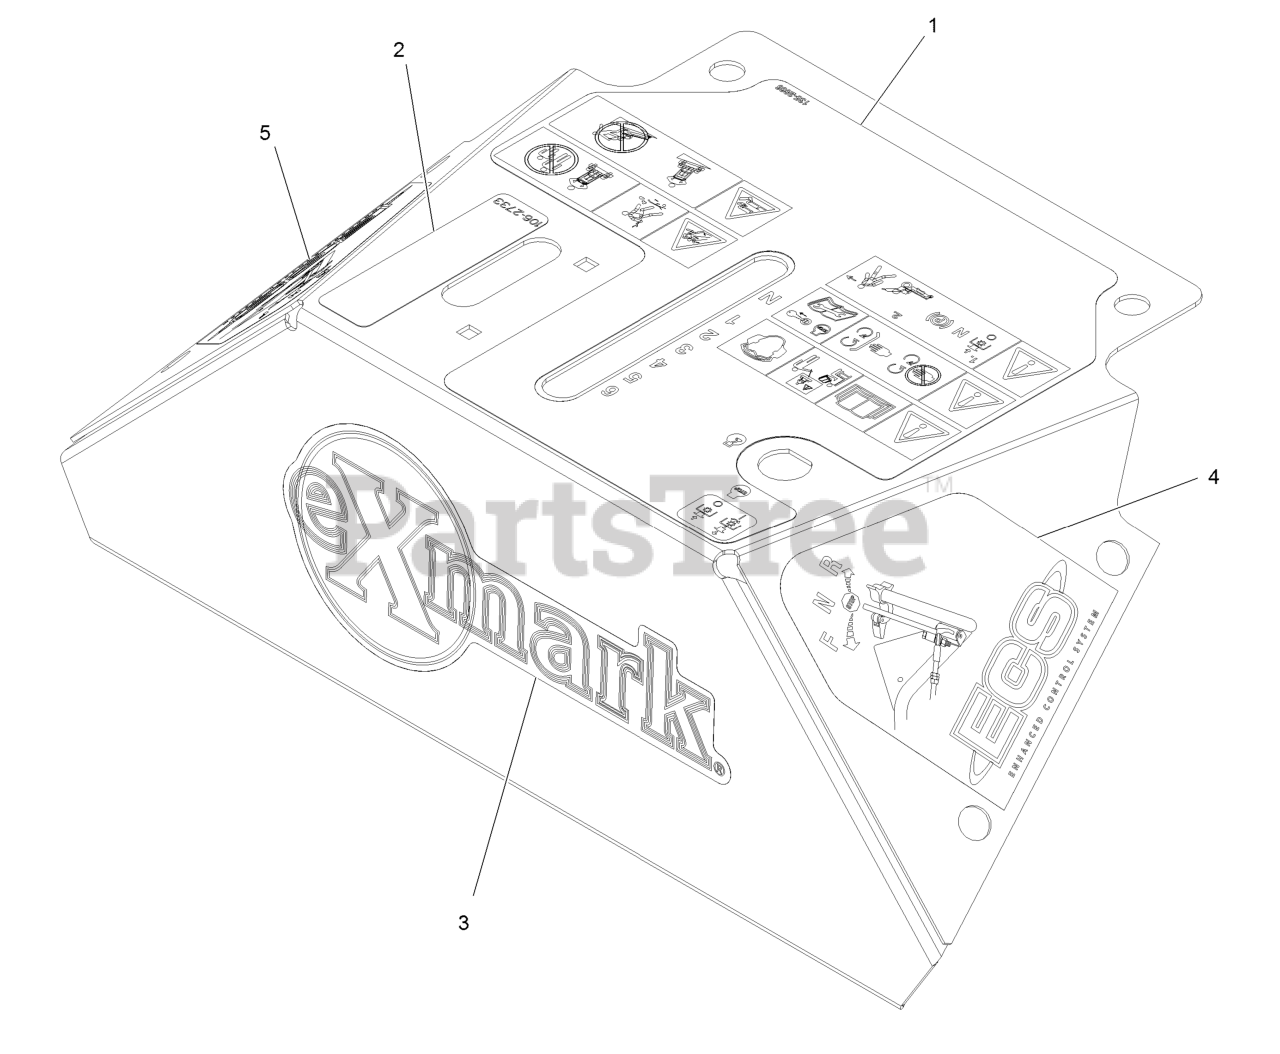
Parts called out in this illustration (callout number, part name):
1	Decal-Console
2	Decal-Throttle
3	Decal, Exmark Logo
4	Decal, Ecs Instruction LH
5	Decal, Ecs Instruction RH
